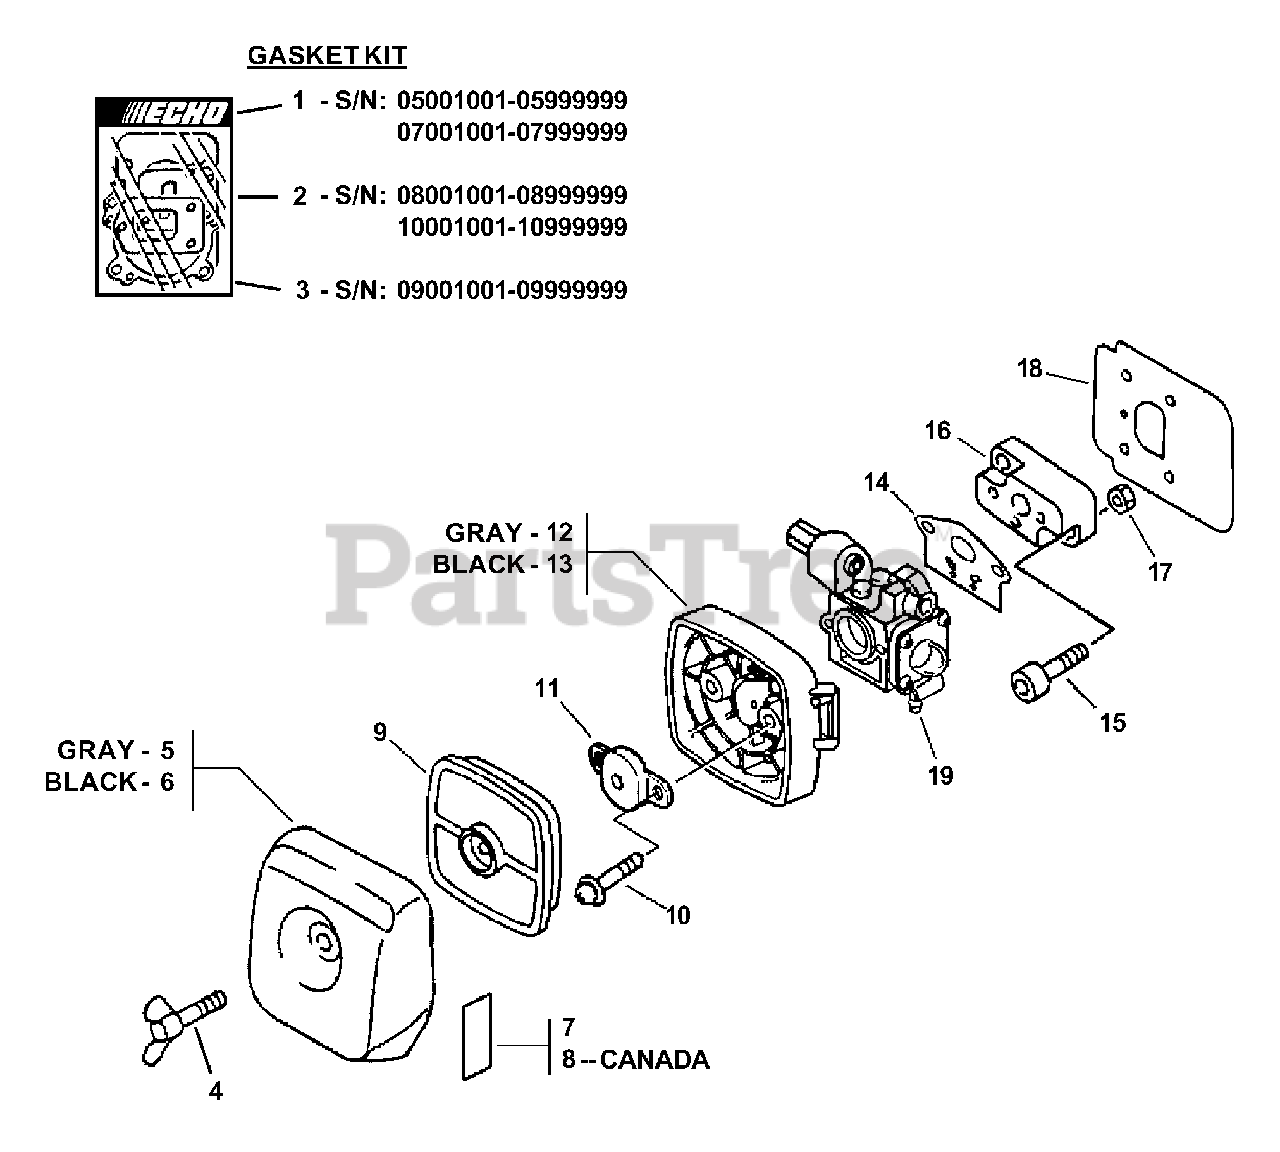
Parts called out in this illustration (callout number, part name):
1	GASKET KIT
2	GASKET KIT
3	GASKET KIT
4	BOLT, WING 5×20
5	COVER, AIR FILTER - GRAY
6	COVER, AIR FILTER - BLACK
7	LABEL, CHOKE
8	LABEL, CHOKE
9	FILTER, AIR - SINGLE LAYER
10	SCREW 5×65
11	PLATE, PREVENT
12	CASE, AIR FILTER - GRAY
13	CASE, AIR FILTER - BLACK
14	GASKET, CARBURETOR
15	SCREW 5×20
16	INSULATOR, INTAKE
17	NUT M5
18	HEAT SHIELD, INTAKE
19	CARBURETOR
